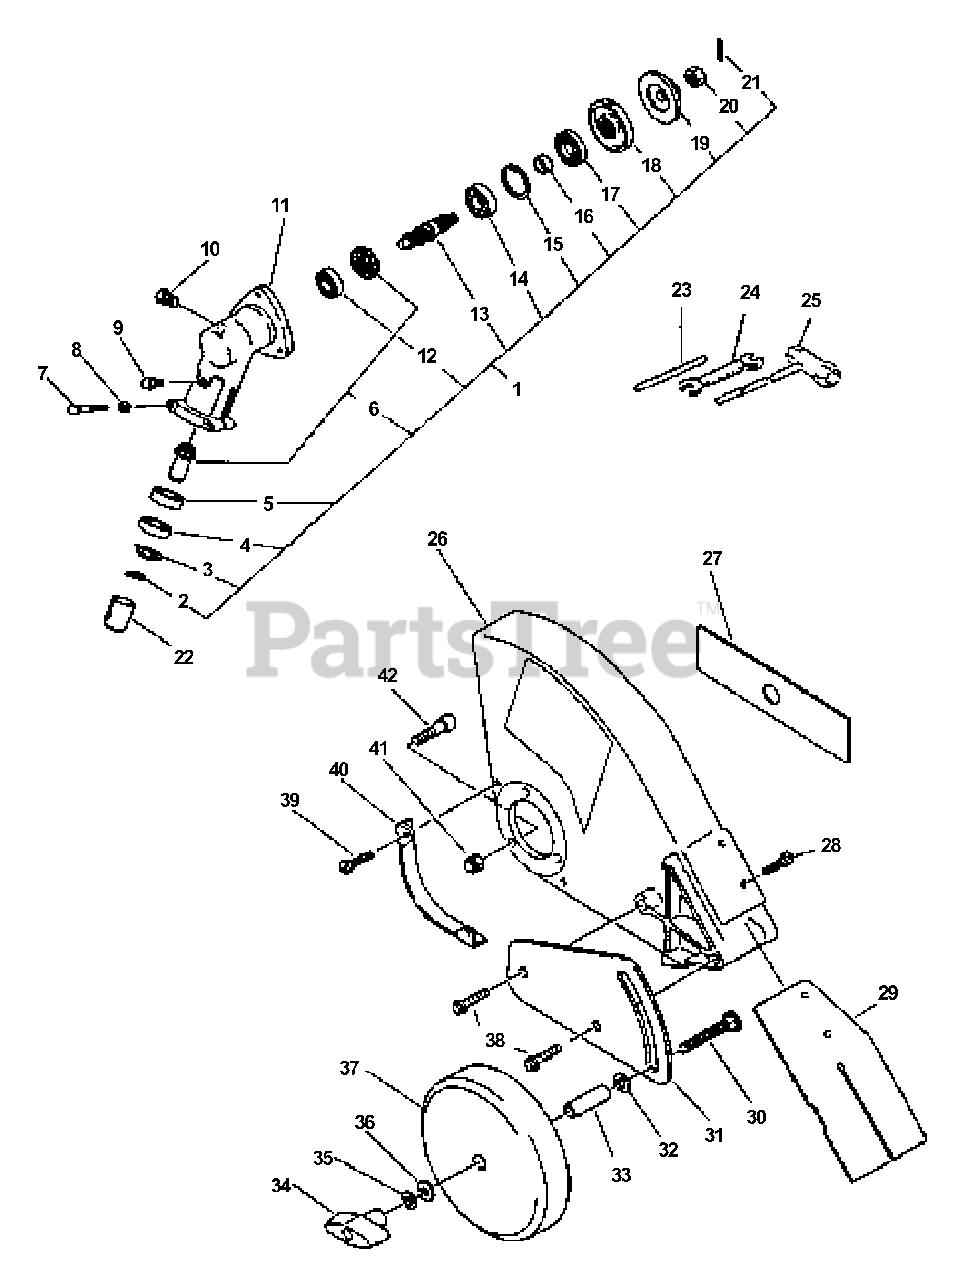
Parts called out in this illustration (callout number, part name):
1	GEAR CASE ASSY
2	RING, SNAP Ø12
3	RING, SNAP Ø22
4	BEARING, BALL 6900Z
5	BEARING, BALL 6900
6	GEAR SET
7	BOLT 5×30
8	WASHER, FLAT 5.5×10×0.8
9	SCREW 5×10
10	BOLT 8×8 SP
11	HOUSING, GEAR CASE
12	BEARING, BALL 609
13	SHAFT, GEAR
14	BEARING, BALL - 6201 C3
15	RING, SNAP Ø32
16	SPACER 11.8×15×9
17	SEAL, OIL 22
18	PLATE, ADAPTER - UPPER
19	PLATE, ADAPTOR - LOWER
20	NUT 10×1.25 LH
21	PIN, COTTER 2×22
22	COLLAR
23	TOOL, LOCKING 5×120 MM
24	SPANNER 8×10
25	T-WRENCH 17x-19 L200
26	SHIELD, DEBRIS
27	BLADE - 2 PK
29	FLAP, DEBRIS
30	BOLT 5/16"-18×2-1/2"
31	BRACKET, WHEEL
32	WASHER, SPRING 10
33	COLLAR 12
34	KNOB, FASTENER
35	WASHER, SPRING 8
37	WHEEL
40	GUARD, SHIELD
41	NUT, LOCK M5
42	BOLT 5×22
